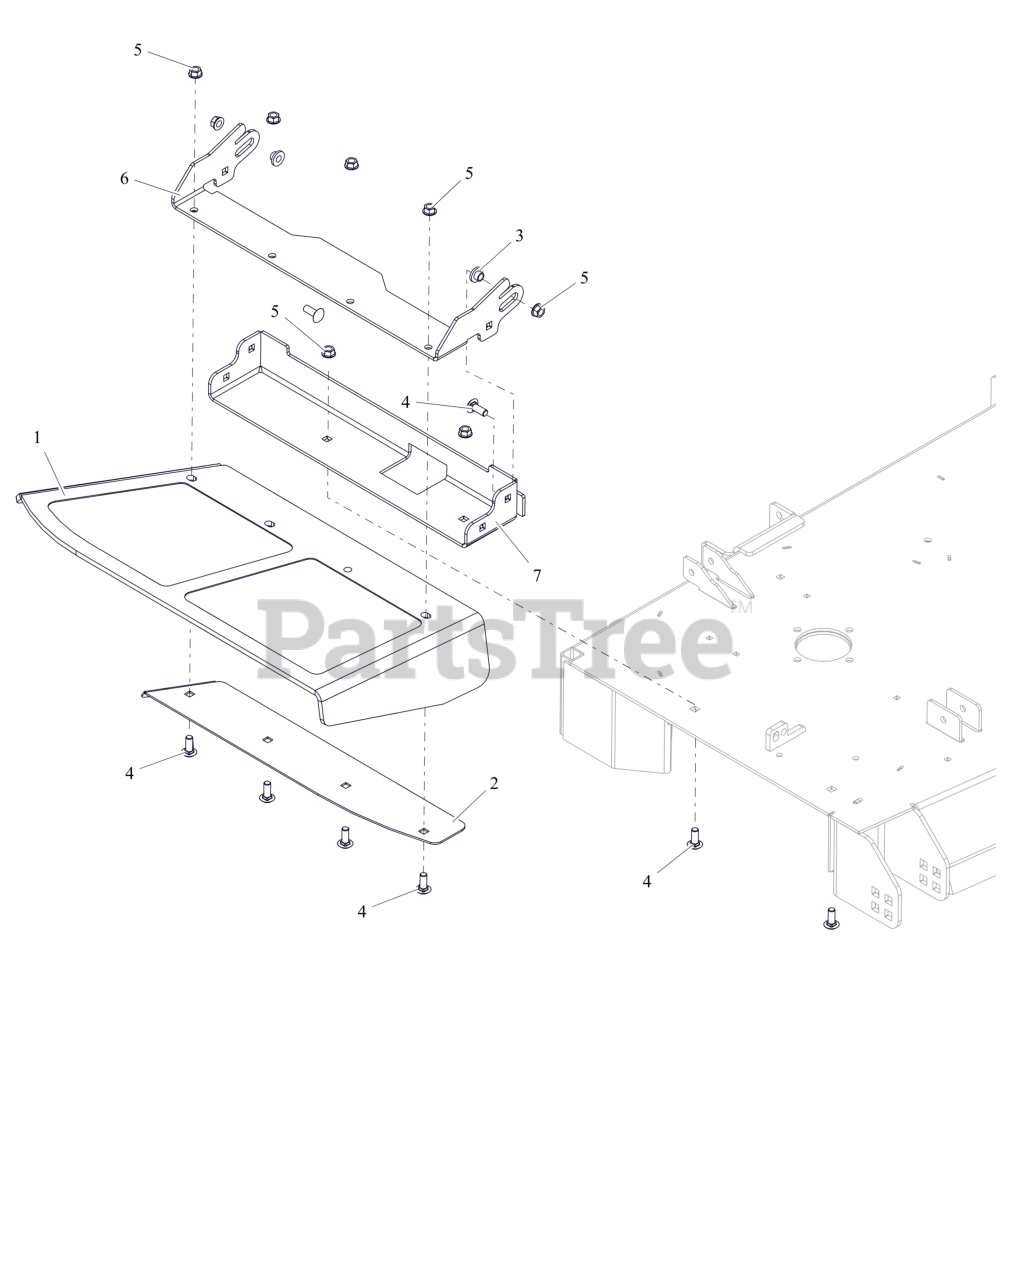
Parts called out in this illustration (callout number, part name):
1	CHUTE, 72" FORMED RUBBER DISCH
2	72" DISCH CHUTE CLAMP PLT -RED
3	BSHG-FLG .385X.500X.875X.406
4	BLT,RHSSN .38-16X1.00 G5 ZCC
5	NUT-LK-CTR-FLG .375-16 GF ZCC
6	BRKT, CHUTE MTG (RED)
7	BASE, DISCHARGE CHUTE MTG (RED) W/ SAFETY DECALS
